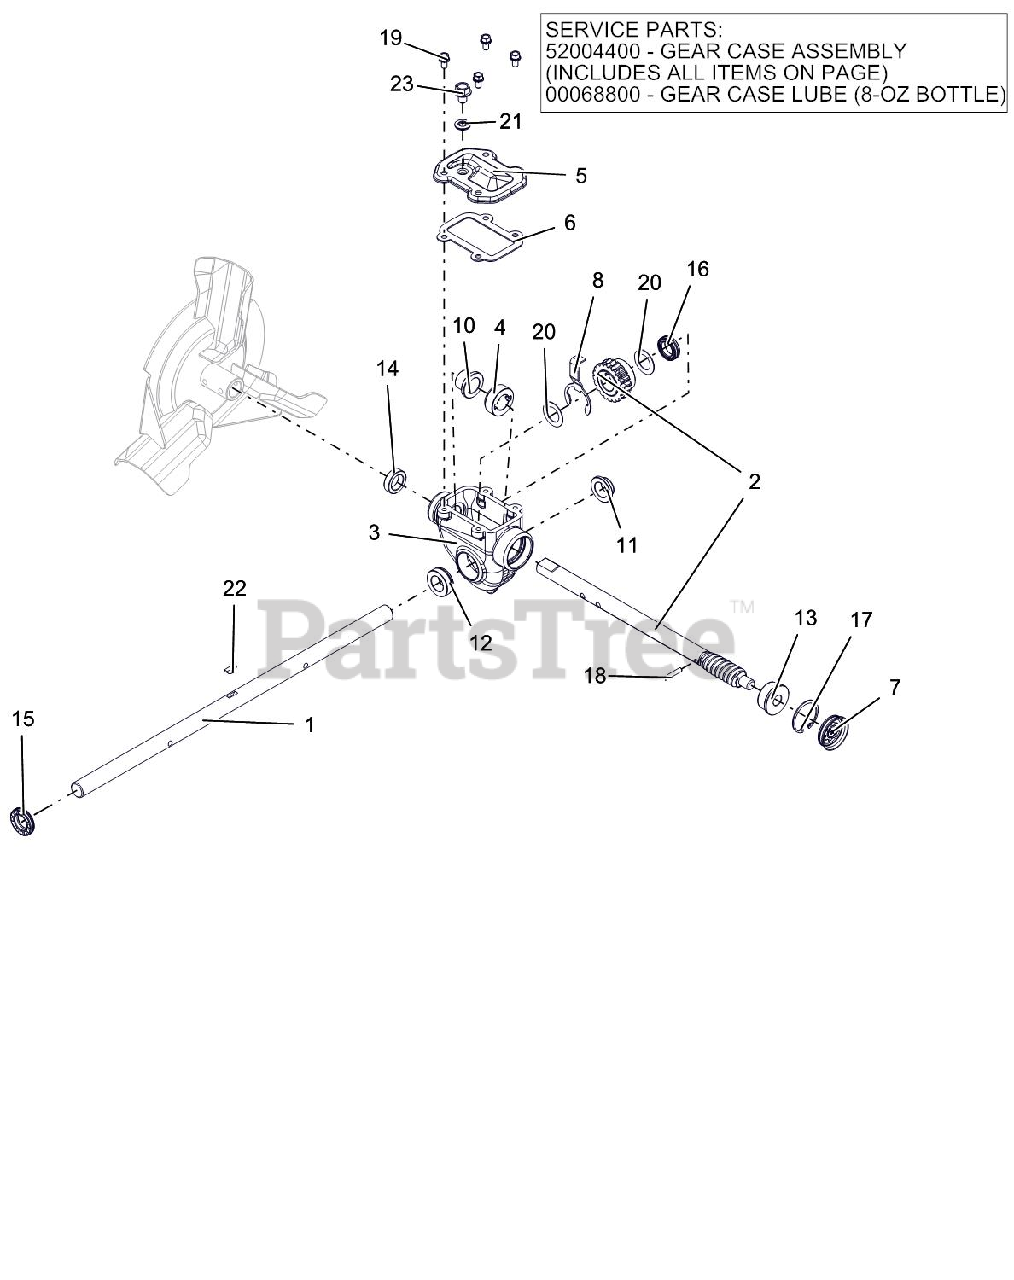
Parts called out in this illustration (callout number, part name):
1	SHAFT, RAKE - 20" (.750 DIA)
2	SHAFT AND WORM GEAR ASSEMBLY
3	GEARCASE, COMPACT MACHINED
4	THRUST COLLAR, .75" ID SLIPFIT
5	COVER, TOP - COMPACT
6	GASKET, TOP - COMPACT GEARCASE
7	COVER, GEAR CASE 1.50"
8	BUSHING RETAINER, COMPACT
10	BSHG-FLG .755X.878X.75X1.25
11	BSHG-FLG .755X.878X.424X1.25
12	BSHG-FLG COMPACT, RIGHT
13	BSHG-FLG .503X1.303X.62X1.465
14	SEAL-OIL .748X1.125X.312 TB2-H
15	SEAL-OIL .748X1.300X.250 TBC29
16	SEAL-OIL .748X1.125X.312 TBC29
17	RG-RTNG-INT 1.500X.050
18	PIN-STR .188X1.00 6150
19	BOLT, SEMS .25-20X.50 GR5 YWZC
20	WSHR-FL-STL .760X1.225X.032 YZ
21	WSHR-BND-SEAL .38X.75X.11 GALV
22	KEY-WDRF .19X.63 HRD #61
23	@SCR-ROLOK .38-16X.50 HWH YWZC
24	GEAR CASE, 24" IRON SM TOP-LD
25	ARIENS L3 LUBE, 8 OZ BOTTLE
